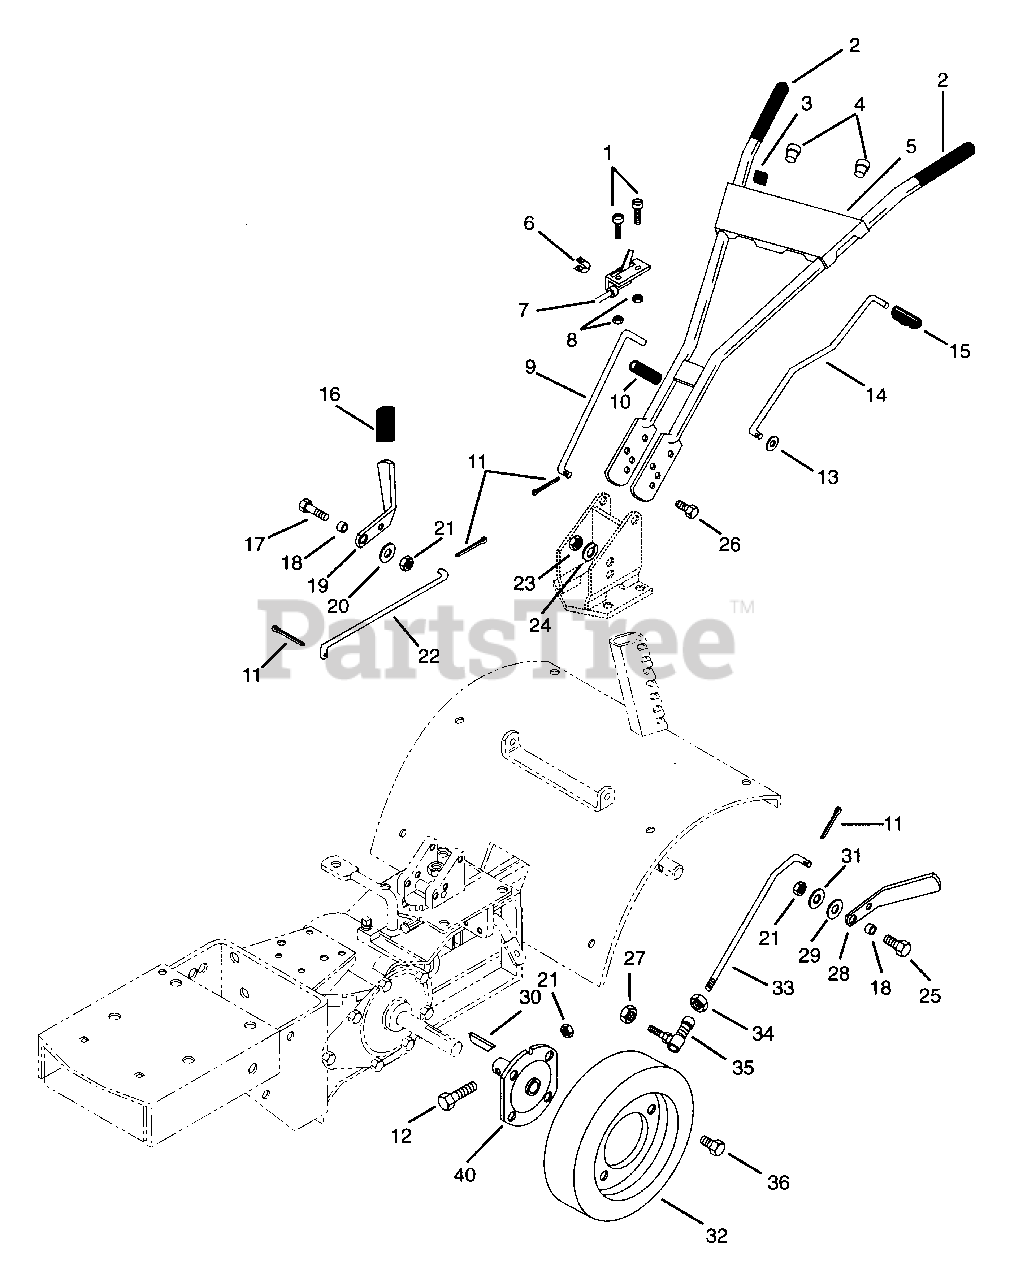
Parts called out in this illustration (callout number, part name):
1	SCR-MCH 10-24X.50 SLRH BL
2	HANDLEGRIP
3	KNOB, CONTROL-THROTTLE
4	SNAP BUSHING
5	HANDLEBAR
6	OUTPUT GEAR
7	THROTTLE CONTROL B&S RT8020
8	NUT-KEPS 10-24 PL
9	POSITION ROD
10	GRIP - 5/16 ID X 2 7/8 - BLACK
11	PIN-COTR .09X.75 PL
12	BLT-HEX .31-18X2.00 PL GR2
13	WSHR-FL-STL.344X.688X.065PL
14	CLUTCH ROD
15	GRIP - 3/8 ID X 2 7/8 - BLACK
17	BLT-HEX .31-18X1.25 PL GR2
18	SPACER BUSHING .5 X .32 X .21
19	DRIVE CLUTCH HANDLE
20	WSHR-FL-STL .38X.875X.083 PL
21	NUT-LK .312-18 GR A PL
22	DRIVE CLUTCH ROD
23	NUT-HEX .375-16
24	WSHR-LK .375X.115 HVY PL
25	BLT-HEX .31-18X.75 PL GR2
26	BLT-HEX .38-16X1.00 PL
27	NUT-LK-CTR .312-24 PL
28	TILLER CLUTCH HANDLE
29	SPACER .344X1.000X.375
30	KEY-FTHR .25X1.875X.25 SAE
31	WSHR-FL-STL .344X1.375X.075 PL
32	T/WHL ASSY 4.80-8
33	TILLER CLUTCH ROD
34	NUT-HEX .312-24 PL
35	SNAP IN BALL JOINT
36	SCR-TAP .500-20X.62 HH PL
37	WHEEL HUB
